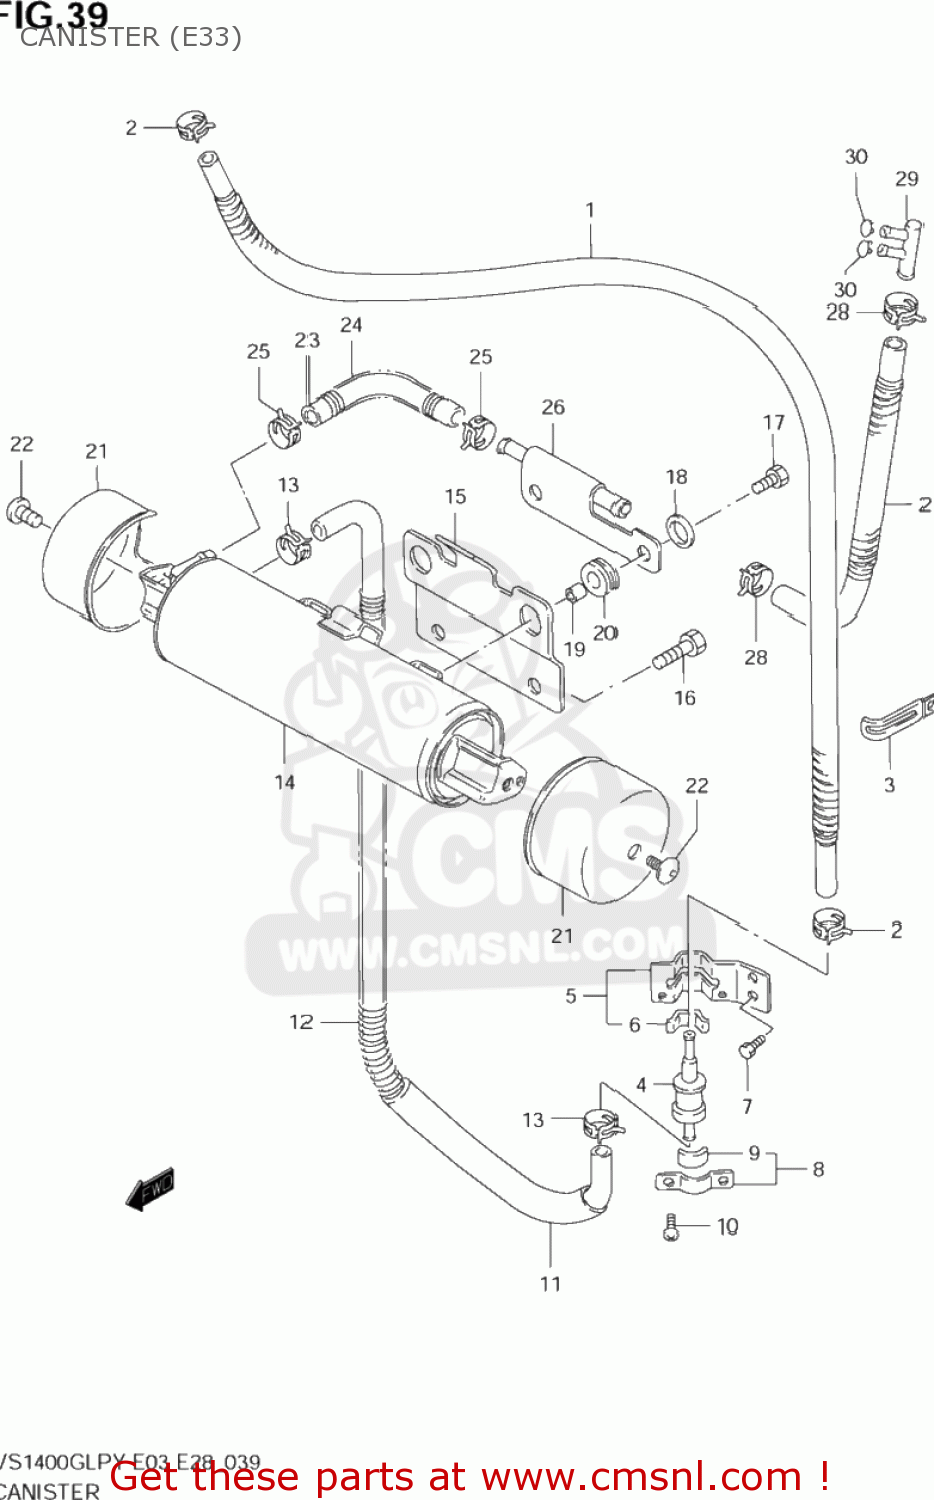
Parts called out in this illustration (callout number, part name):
1	HOSE,JOINT FUEL TANK
2	CLIP
3	CLAMP(L:65)
4	VALVE,FUEL TANK BREATHER
5	BRACKET,TANK BRTHR VALVE
6	CUSHION
7	BOLT
8	PLATE,FUEL TANK BREATHER NO.2
9	CUSHION
10	SCREW
11	HOSE,VALVE & CANISTER JOINT
12	SPRING
13	CLIP
14	(CA) CANISTER ASSEMBLY,CHARCOAL
15	PLATE,CANISTER FITING
16	BOLT
17	BOLT
18	WASHER(6.5X22X1.6)
19	SPACER(6.1X9X7.5)
20	CUSHION
21	COVER,CANISTER
22	SCREW(6X10)
23	HOSE,CANISTER PIPE JOINT
24	SPRING
25	CLIP
26	PIPE,CANISTER
27	(CA) HOSE,PIPE JOINT
28	CLIP
29	SEPARATOR
30	CLIP
